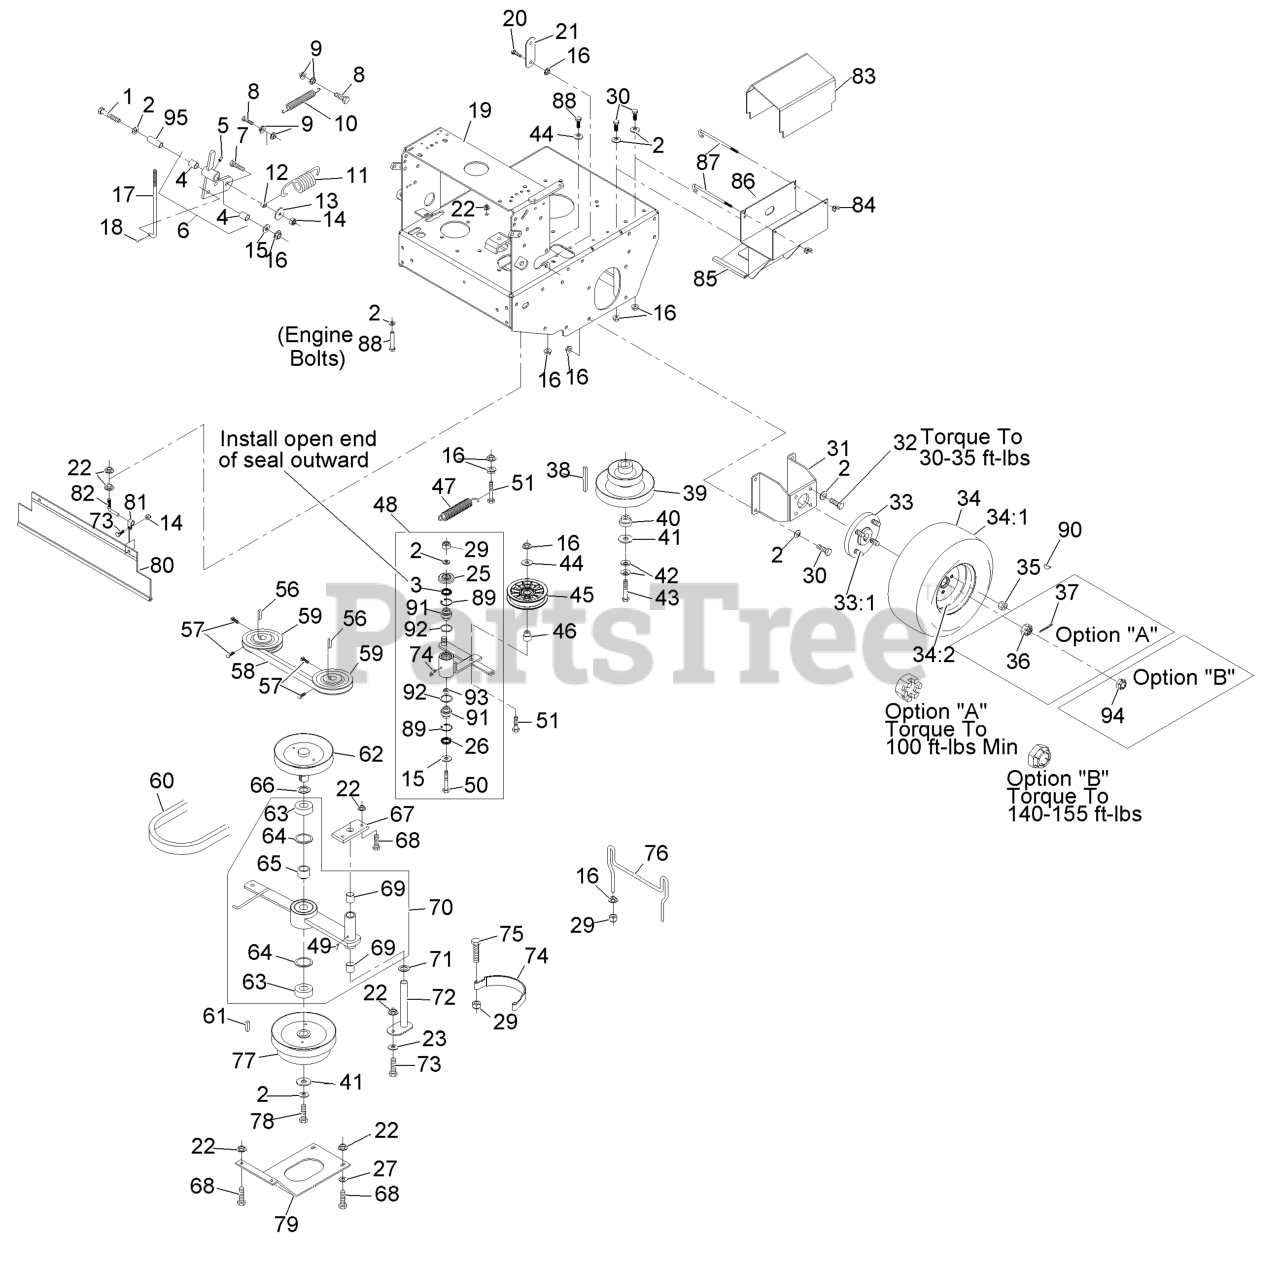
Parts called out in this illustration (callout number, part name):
1	SCREW-HH
2	WASHER-BELLEVILLE
3	SEAL-LIP, SINGLE
4	SLEEVE-BEARING
5	FITTING-GREASE
6	ASM,PIVOT W/BUSHINGS
7	SCREW-HH
8	SCREW-HH
10	SPRING,EXTENSION
11	SPRING,EXTENSION
12	SPACER,CLUTCH ANCHOR
14	NUT-LOCK, NI
15	WASHER-FLAT
16	NUT-HHF, WHIZ
17	LINKAGE,LOWER
18	PIN-COTTER
19	KIT,TTHP ENG DECK
20	SCREW-HH
21	ARM-LIFT, DECK
23	WASHER-SPRING
25	GUARD-TOP
26	SEAL-LIP, DOUBLE
27	WASHER-FLAT
29	NUT-LOCK, NI
30	SCREW-HH
31	WLD,MOTOR MOUNT 48&52
32	SCREW-HH
33:1	STUD-WHEEL
34	WHEEL AND TIRE ASM
34:1	TIRE-TURFMASTER
34:2	RIM-WHEEL
35	NUT-LUG
36	NUT-HEX, SLOTTED
37	PIN-COTTER
38	KEY,MACH 1/4X1/4X2-5/8
39	SHEAVE, DRIVE
40	BUSHING,CLUTCH KEEPER
42	WASHER-SPRING
43	SCREW-HH
44	WASHER-FLAT
45	PULLEY-IDLER, FLAT
46	BUSHING-IDLER
48	KIT,PUMP IDLER ARM TTHP
49	FITTING-GREASE
50	SCREW-HH
51	SCREW-HH
57	SCREW-SET
58	BELT,COG A 50.55
59	SHEAVE ASM
60	BELT,B-38.0
62	SHEAVE, W/ SHAFT
63	BEARING,CLUTCH SHAFT
64	RING-SNAP
65	SPACER,CLUTCH BEARING
66	WASHER-SPACER
67	PLATE-CLUTCH PIVOT
68	SCREW-HH
69	SLEEVE,BEARING
70	ASM,CLUTCH ARM W/BEARING
71	WASHER-SPACER
72	WLD,PIN PIVOT
73	SCREW-HH
74	BAND,BRAKE BLADE
75	SCREW-HH
76	GUIDE,BELT (PLTD)
77	SHEAVE,6.75 W/DRUM
78	SCRW,CAP HH
79	PLATE-GUARD
80	SHIELD-DRAG
81	CLIP-LOOM
82	MOUNT,DRAG SHIELD
83	COVER,BATTERY W/DECAL
84	WINGNUT
85	TRIM-LOK
86	ASM,BATTERY STAND W/TRIM
87	BOLT - HOLD DOWN
88	SCREW-HH
89	RING-SNAP
90	KEY-WOODRUFF
91	BEARING-SPHERICAL
94	NUT-LOCK
95	BUSHING
